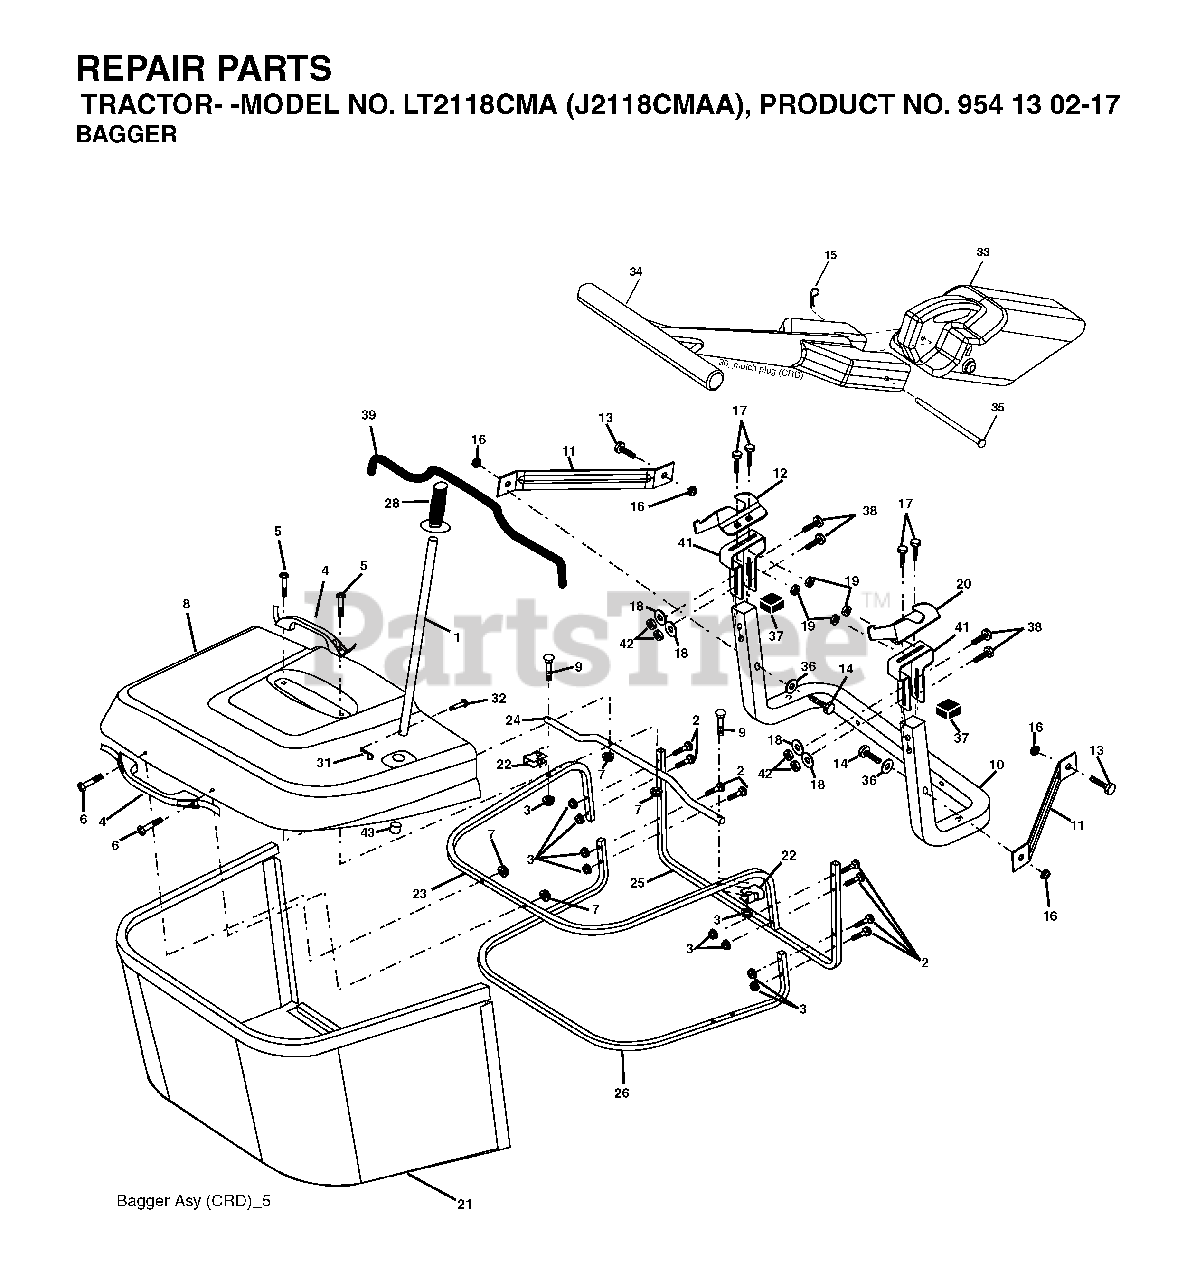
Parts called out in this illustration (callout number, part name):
1	TUBE HANDLE
3	NUT T
5	SCREW.PAN.HEAD
11	BRACKET
14	BOLT-HEX EAK
15	RETAINER-SPRNG RB
16	NUT LOCK FLG 3/8-16 UNC
17	BOLT
18	WASHER M
19	NUT LOCK HEX FLANGE 5/16-18
20	BRACKET
21	GRASS BAG
22	BRACKET
23	TUBE
24	TUBE
26	TUBE
28	GRIP.HANDLE.BLACK
31	RETAINER CLIP
32	RIVET,DRILLED
33	MULCH PLUG, CTH150
35	PIN
36	WASHER
38	BOLT.5/16-18X2.5
41	BRKT, BAGGER
42	NUT.71038.31-18.HEX.NYLOCK
43	PLUG, TUBING END
